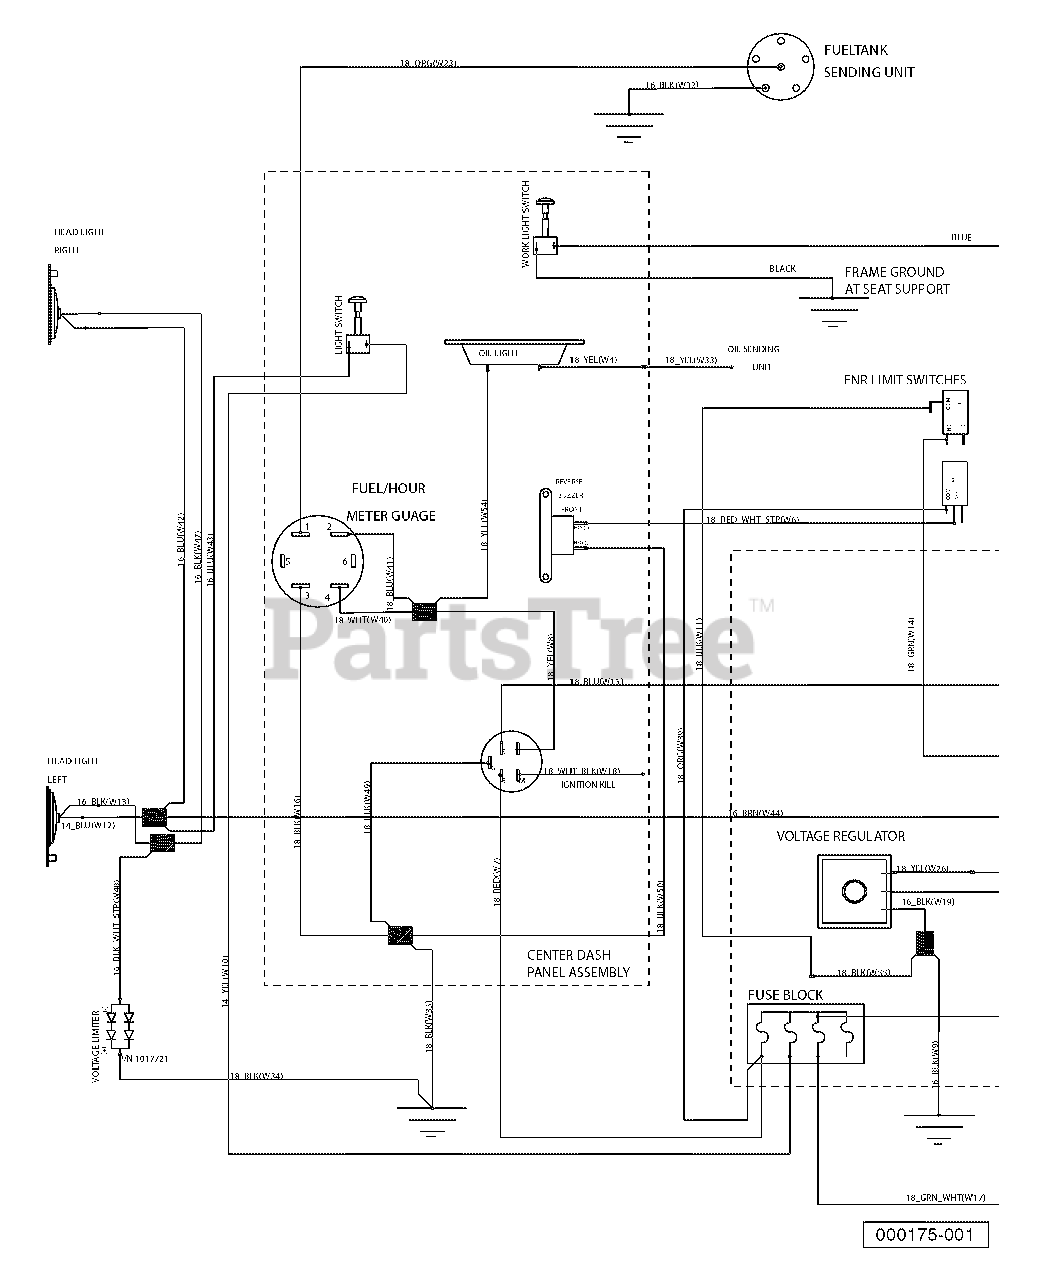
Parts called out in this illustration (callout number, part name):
1	Wire Assy, #6 Black
2	Wire Assembly #6 Red
3	Wire Assembly, #10, Uninsulated
4	Wire Assy, #10 Red
5	Wire Assy, #6 Green
6	Asm, Wire Harness
